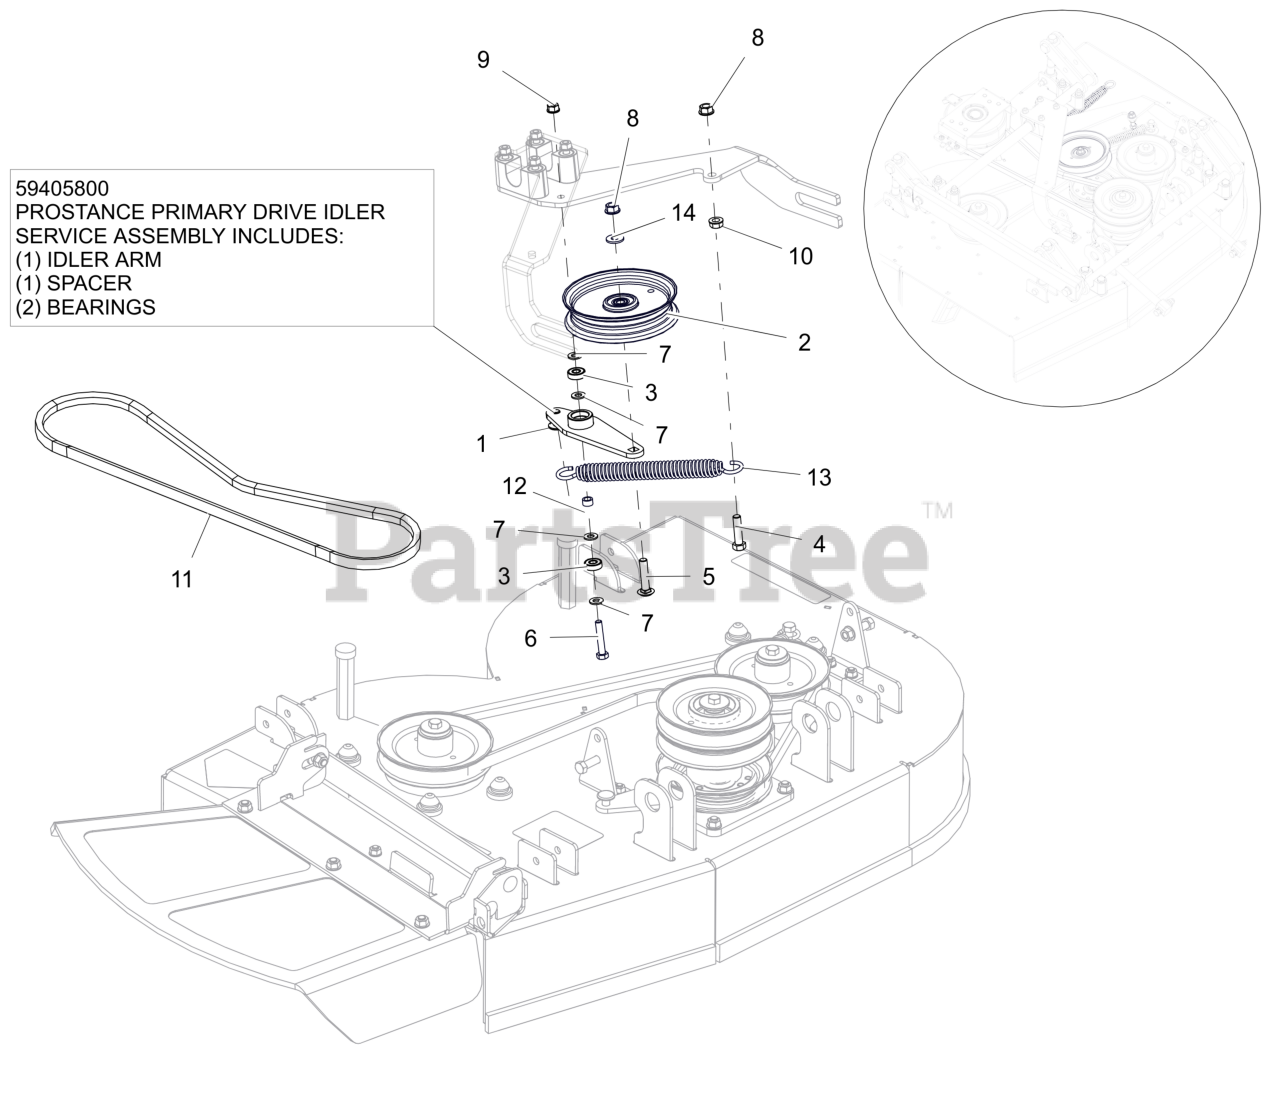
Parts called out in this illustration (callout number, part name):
1	WLDMT, IDLER ARM
2	IDLER- FLAT - 5.00" X .75"
3	BRG-BALL .315X.866X.276(608)
4	BLT, HEX .38-16X1.50 G5 ZCC
5	BTL,RHSSN .375-16 X 1.75 G5 ZCC
6	BLT, HEX .31-18X1.75 G5 ZCC
7	WSHR, HRDN 0.344X0.688X0.065
8	NUT-LK-CTR-FLG .375-16 GF ZCC
9	NUT,LK-CTR-FLG .31-18 GF ZCC
10	NUT, SPNLK-FLG .38-16 G5 ZCC
11	V-BELT, 5L RAW EDGE EPDM
12	SPCR- SLV .344 X .500 X .283
13	SPRING- EXTENSION
14	WSHR,FLT .375X.875X.083 ZCC
